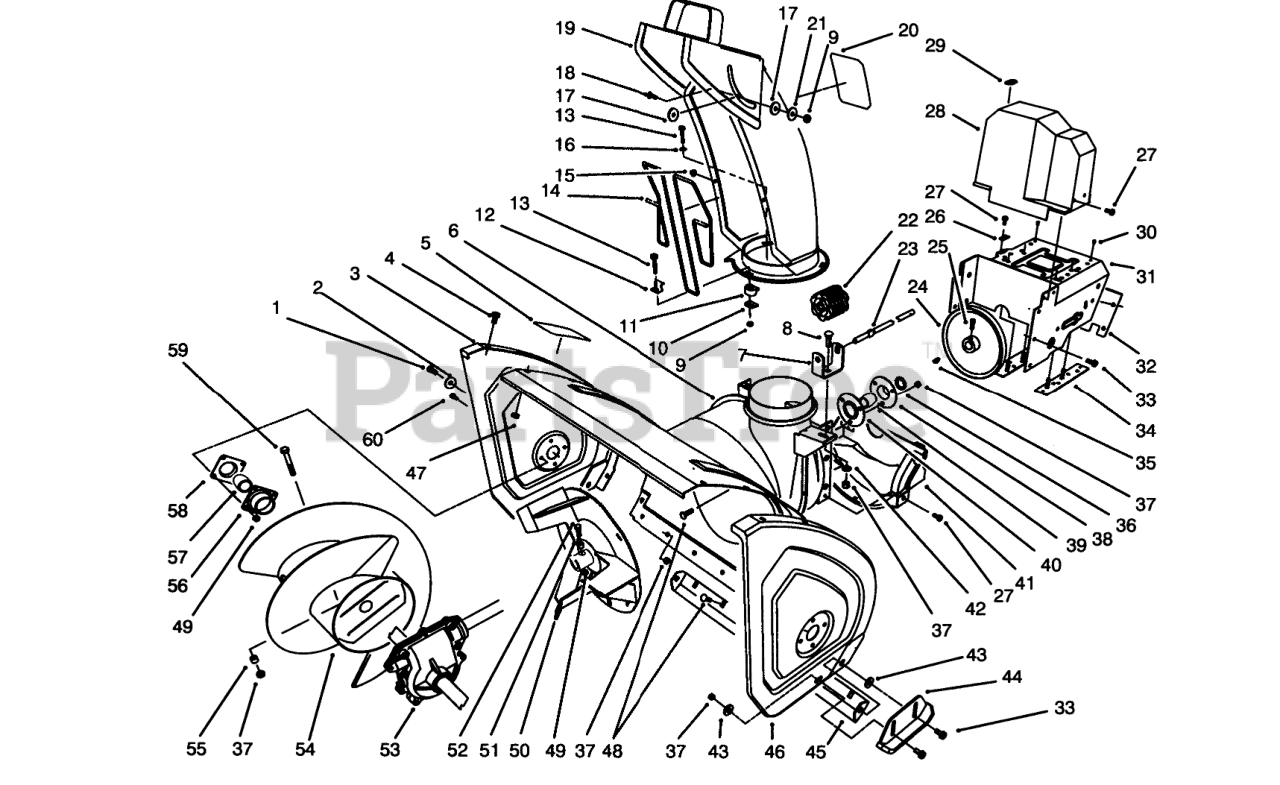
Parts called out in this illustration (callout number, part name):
1	SCREW-HH
2	WASHER
3	Plate-Side
4	SCREW-HHF
5	DECAL-WARNING, AUGER
6	Housing-24"
7	BRACKET-WORM, CHUTE
8	BOLT-CARR
9	NUT-LOCK, NI
10	PLATE-RETAINER, CHUTE
11	RETAINER-CHUTE
12	CLIP-GUARD, CHUTE
13	SCREW-HSH
14	GUARD-CHUTE
15	NUT-PUSH
16	WASHER-FLAT
17	WASHER-PLASTIC
19	Assembly
20	Decal-Danger
21	WASHER-FLAT
22	GEAR-WORM
23	ROD-CHUTE, LOWER
24	PULLEY-IMPELLER
25	SCREW-SET, SQH
26	RETAINER-CABLE
27	SCREW-HWH
28	COVER-BELT, UPPER
29	COVER-CABLE
30	RIVET-POP
31	Frame-Engine
32	Cover-Frame, Engine
33	SCREW-HHF
34	LH FRAME PLATE ASM
35	KEY-WOODRUFF
36	WASHER-THRUST
37	NUT-LOCK, NI
38	Flange-Bearing (Rear)
39	BEARING-BALL
40	Flange-Bearing (Front)
41	COVER-BELT, LOWER
42	WASHER-PLAIN
43	WASHER
44	Skid
45	Blade-Scraper
46	Plate-Side
47	NUT-LOCK, NI
48	SCREW-CARR
49	NUT-LOCK, NI
50	Impeller
51	SPACER
52	SCREW-HHF
53	AUGER GEARCASE ASM
54	Auger-R.H.
55	SPACER-HUB, AUGER
56	BEARING-FLANGE, FRONT
57	BEARING
58	BEARING-FLANGE, REAR
59	Auger Bolt
60	SCREW-HH
